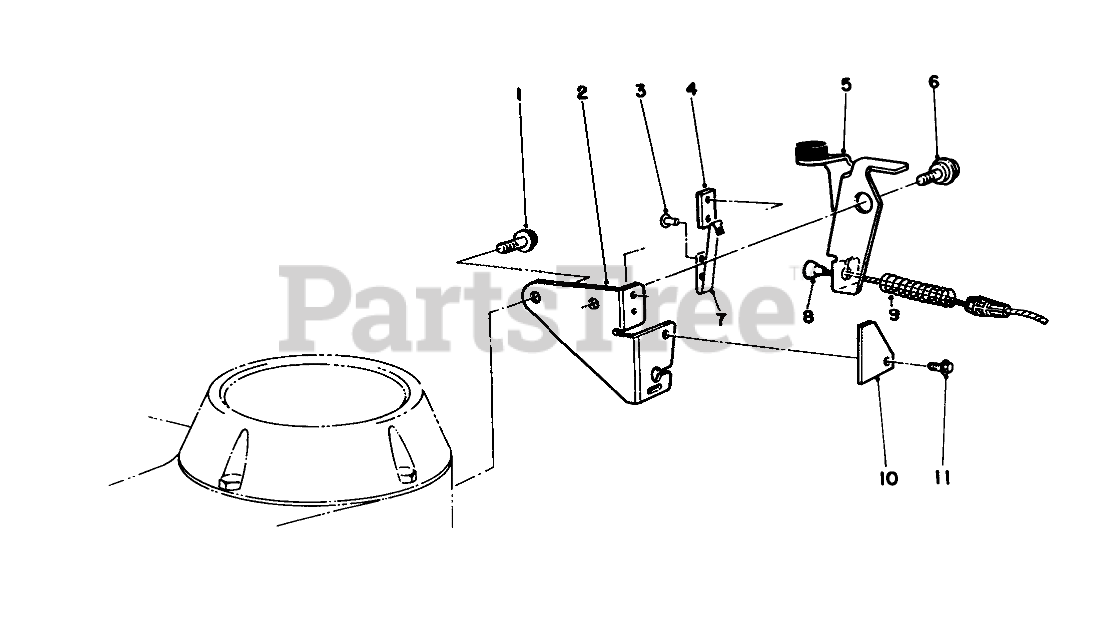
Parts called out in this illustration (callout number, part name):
1	THO FORM SCREW M6 X 1
2	PLATE-BRAKE
3	RIVET-PLASTIC
4	STRAP-INSULATING
5	BRAKE PLATE ASM
6	Screw-Shoulder
7	STRAP-GROUND
8	BRAKE CABLE
9	SPRING-COMPRESSION
10	STOP-GROUND STRAP
11	SCREW-HWH
